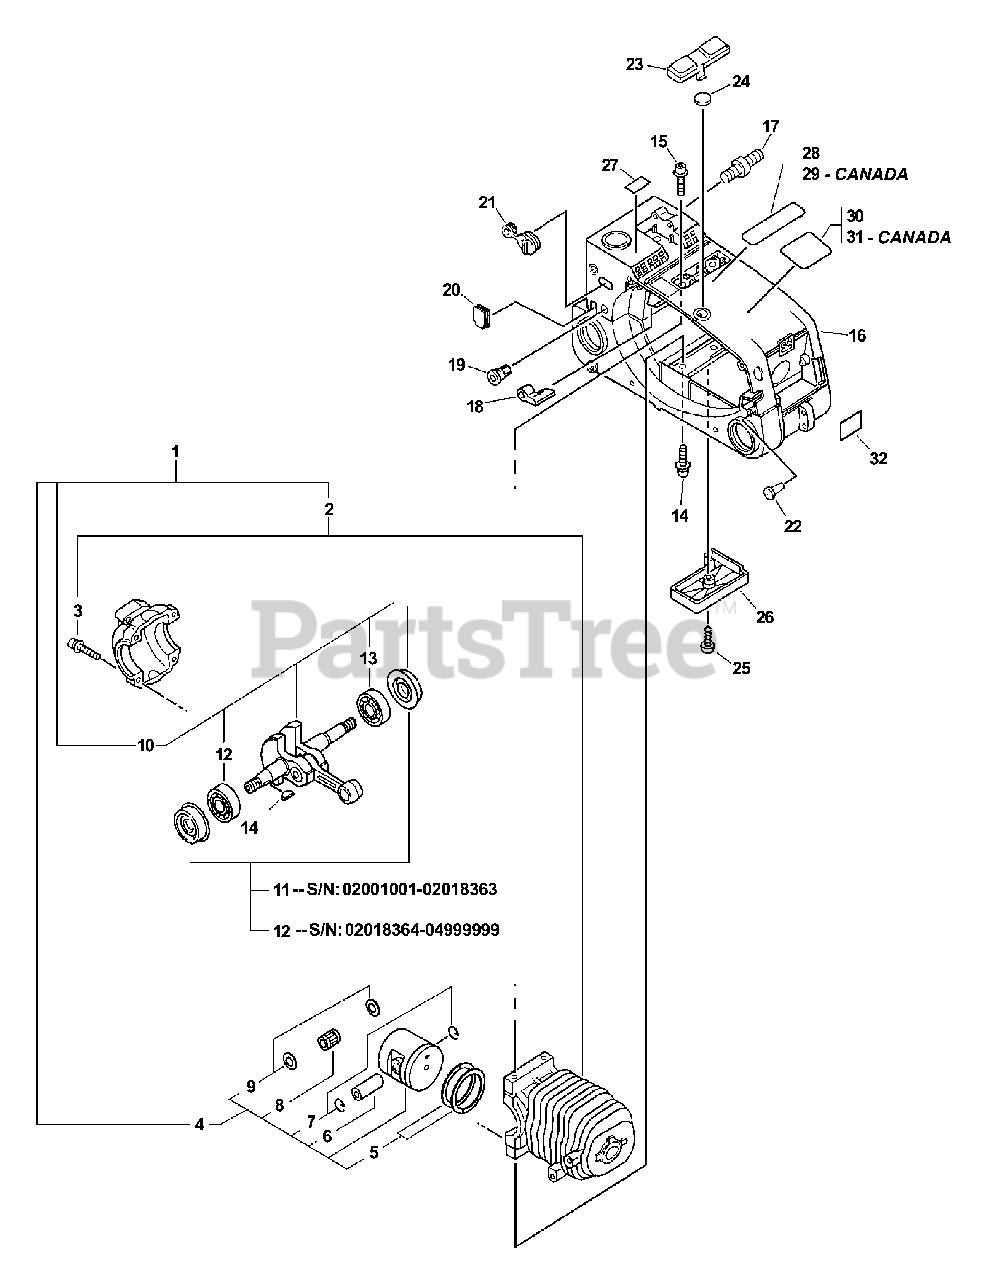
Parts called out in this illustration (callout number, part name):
1	SHORT BLOCK -- SB1069
2	CRANKCASE SET
3	SCREW - 5X25
4	PISTON KIT
5	RING, PISTON
6	PIN, PISTON
7	RING, RETAINING
8	BEARING, NEEDLE
9	SPACER, PISTON
10	CRANKSHAFT ASSY
11	SEAL, OIL
12	SEAL, OIL - 12
13	BEARING, BALL - 6201
15	SCREW - 5X16
16	COVER, ENGINE - GRAY
17	STUD, GUIDE BAR
22	VENT, TANK
23	COVER - GRAY
25	SCREW - 4X16
26	COVER, BOTTOM - GRAY
27	LABEL - PURGE PUMP
28	LABEL - CAUTION -- SPANISH
29	LABEL - NOISE
30	LABEL - KICK BACK
31	LABEL - KICK BACK
32	LABEL - HOT SURFACE
